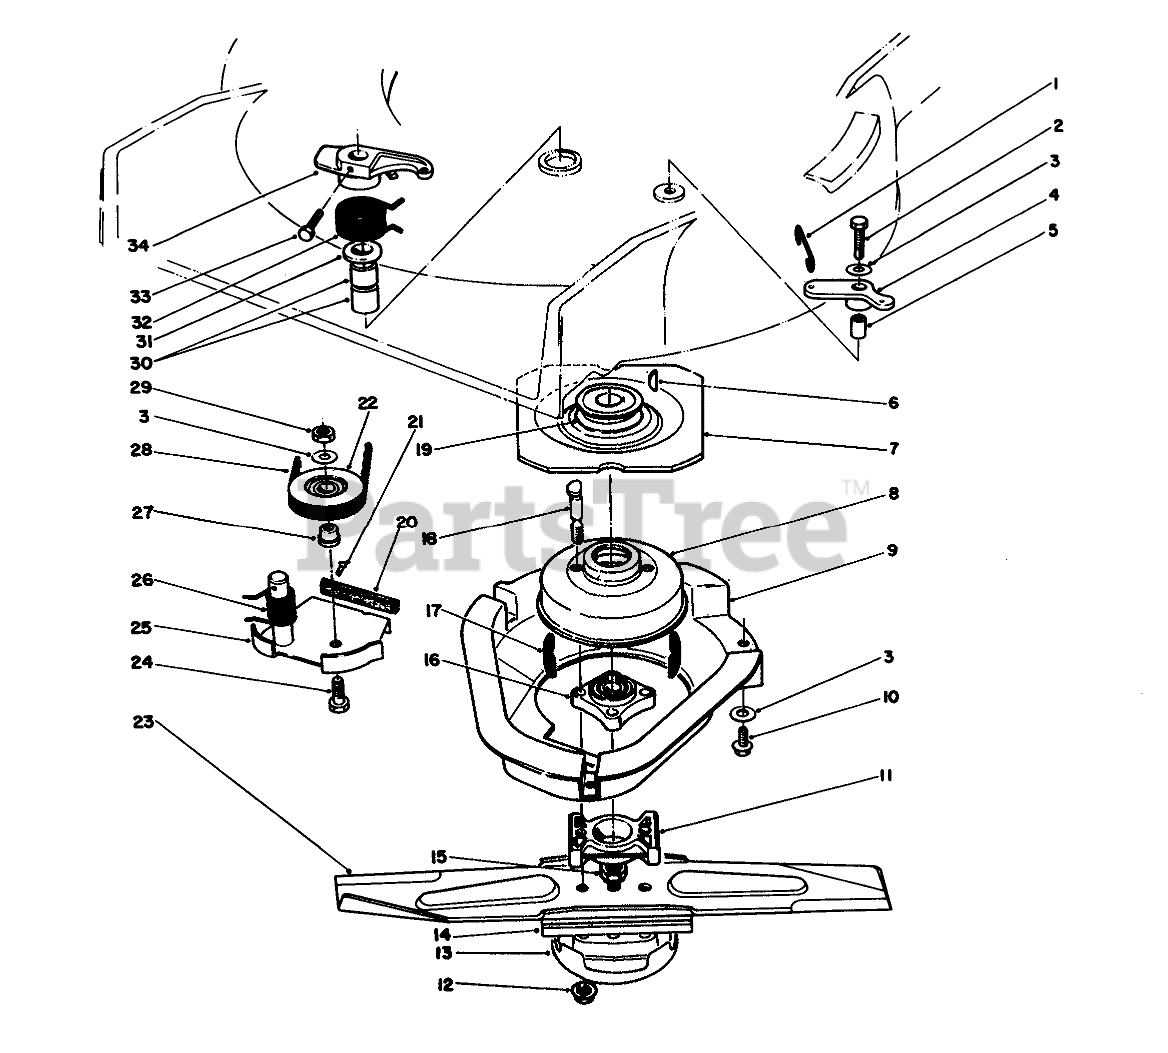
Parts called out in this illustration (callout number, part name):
1	LINK-CONTROL
2	SCREW-HH
3	WASHER-PLAIN
4	BELLCRANK
5	SLEEVE-BELLCRANK
6	KEY-WOODRUFF
7	Flywheel
8	Drum-Brake
9	SHIELD BBC
10	SCREW-HWHTF
11	SPACER-BLADE
12	NUT-LOCK
13	CUP-SCALP, ANTI
14	Stiffener
15	NUT-LOCK, NI
16	HUB ASM
17	DAMPENER-VIBRATION
18	BOLT-BLADE
19	PULLEY
20	Pad-Brake
21	.185 DIA X .375 RT +
22	PULLEY-IDLER
23	Blade
24	SCREW-HH
25	Brake Plate (Incl. Ref. #20 & 21)
26	SPRING-TORSION
27	HUB-PULLEY, IDLER
28	V-BELT
29	NUT-LOCK, NI
30	BEARING
31	WASHER
32	SPRING-TORSION
33	SCREW-HH
34	LEVER
